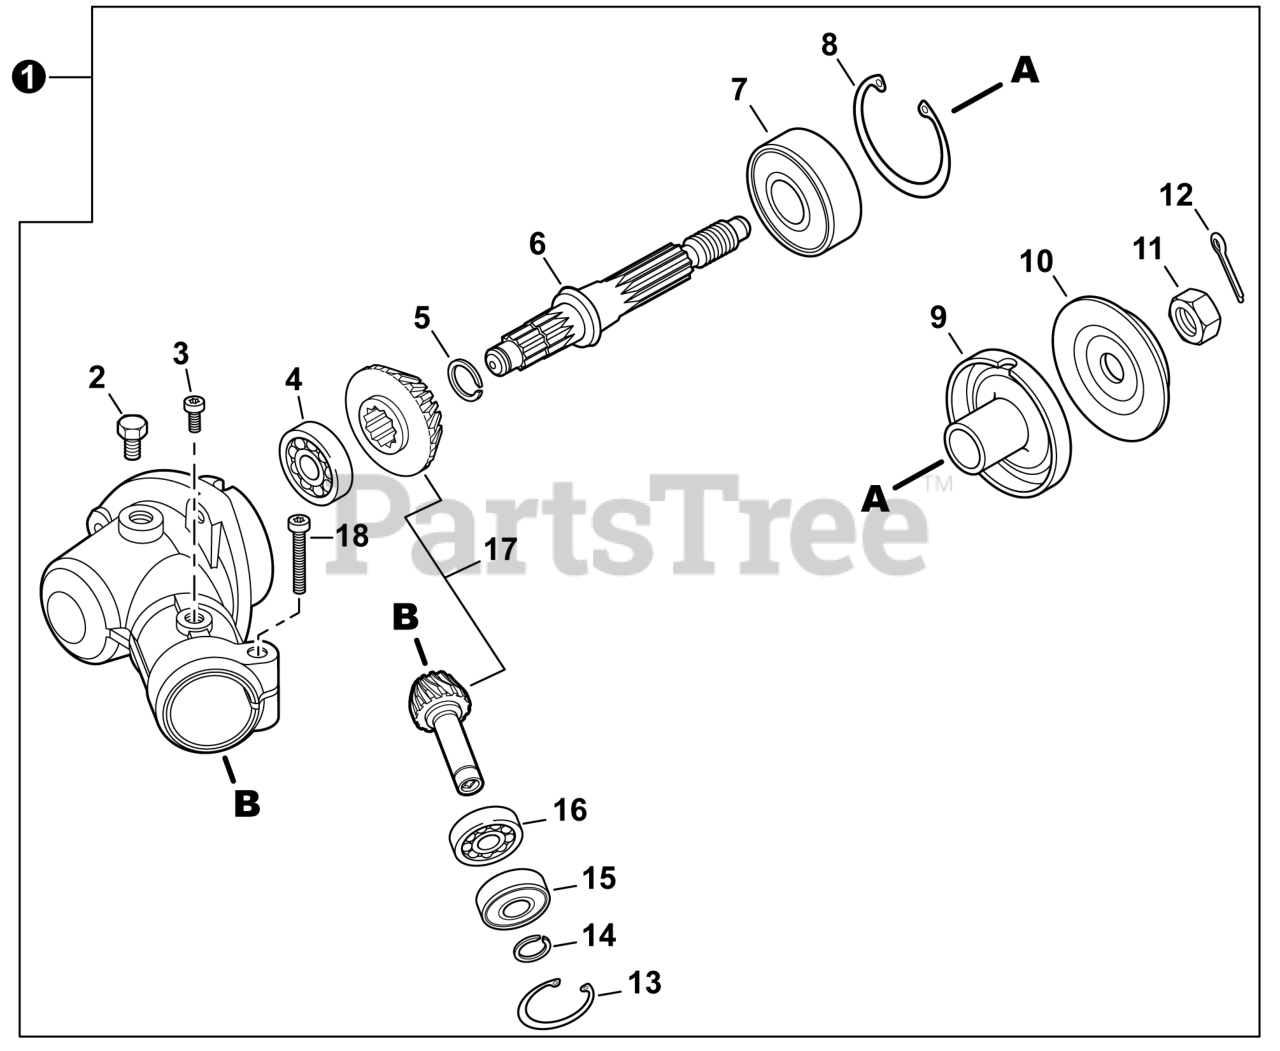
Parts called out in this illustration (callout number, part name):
1	GEAR CASE ASSY
2	BOLT M8x8
3	BOLT, TORX 5x12
4	BEARING, BALL 629A
5	RING, SNAP 12
6	SHAFT, GEAR
7	BEARING, BALL 6302
8	RING, SNAP 42
9	PLATE, ADAPTOR - UPPER
10	PLATE, ADAPTOR - LOWER
11	NUT 10x1.25 LH
12	PIN, COTTER 2x22
13	RING, SNAP 25
14	RING, SNAP 9
15	BEARING, BALL 609ZA
16	BEARING, BALL 609A
17	GEAR SET
18	BOLT, TORX 5x25
